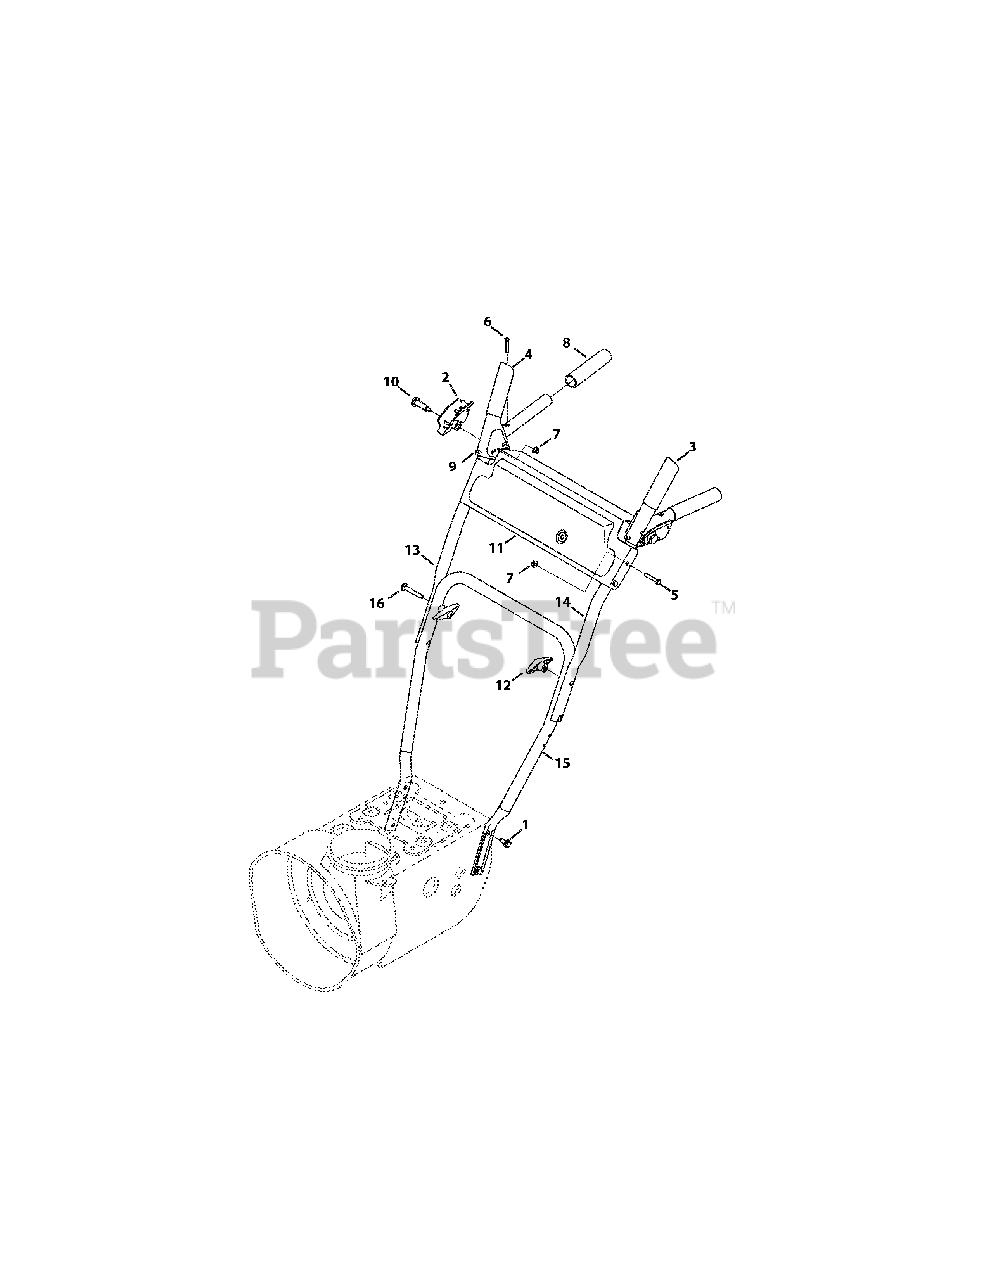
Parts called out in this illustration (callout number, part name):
1	Taptite Screw, 5/16-18 x .750
2	Clutch Lock Handle Assembly, LH
2	Clutch Lock Handle Assembly, RH
3	Engagement Assembly, LH
4	Engagement Assembly, RH
5	Hex Head Screw, 1/4-20 x 1.50
6	Machine Screw, #10-24 x 1.375
7	Flange Lock Nut, 1/4-20
8	Grip, 1.0 ID x 5.0 LG
9	Rubber Bumper, .62 OD x .22 Thick
10	Shoulder Screw, .437 x 1.345 x 1/4-20
11	Handle Panel
12	Wing Knob
13	Upper RH Handle
14	Upper LH Handle
15	Lower Handle
16	Carriage Screw, 5/16-18 x 2.25
